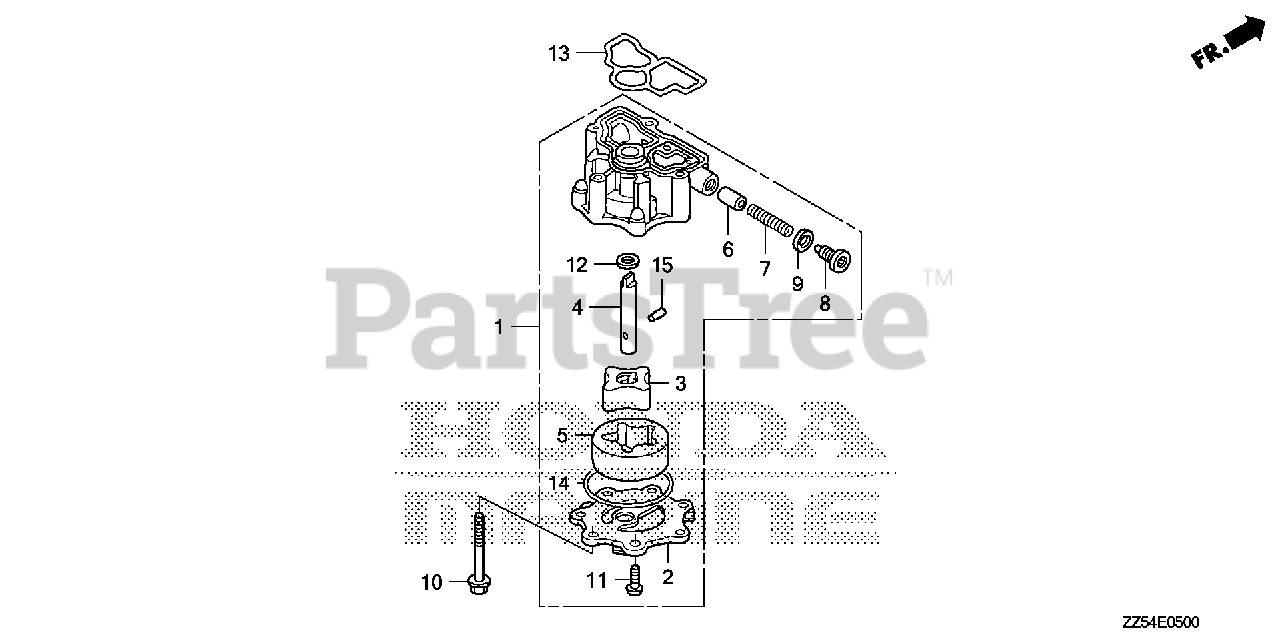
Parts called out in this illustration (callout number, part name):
1	PUMP ASSY., OIL
2	COVER, OIL PUMP
3	ROTOR (INNER)
4	SHAFT, OIL PUMP
5	ROTOR A (OUTER)
6	VALVE, RELIEF
7	SPRING, RELIEF VALVE
8	BOLT, SEALING (14MM)
9	WASHER, SEALING (14MM)
10	BOLT, FLANGE (6X55)
11	SCREW, PAN (6X16)
12	WASHER, THRUST (12MM)
13	O-RING, PUMP COVER
14	O-RING (54X2.4) (ARAI)
15	ROLLER (5X17.8)
